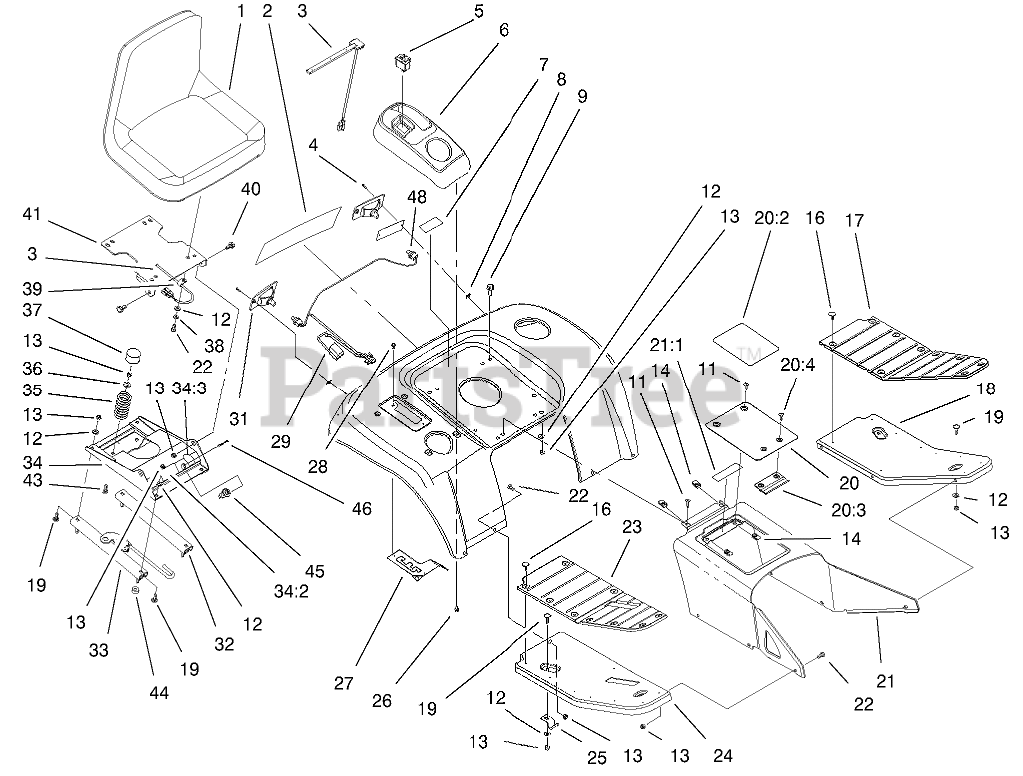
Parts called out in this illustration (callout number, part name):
1	SEAT
2	DECAL - FENDER
3	SWITCH-SEAT
4	SCREW-PPH
5	SWITCH-CRUISE
6	POD-CONTROL
7	DECAL - USA
8	NUT-SPEED
9	SCREW-HHF
11	SCREW-HH
12	WASHER-PLAIN
13	NUT-LOCK, NI
16	FASTENER-PANEL
17	PAD-FOOTREST, LH
18	FOOTREST-LH
19	SCREW-CARR
20	COVER / DECAL ASM
20:2	DECAL-DANGER
20:3	RETAINER-COVER
20:4	SCREW-PPH
21	TUNNEL ASM
21:1	DECAL-DANGER
22	SCREW-HH
23	PAD-FOOTREST, RH
24	FOOTREST-RH
25	BRACKET-FOOTREST
26	SCREW-HHFTF
27	GATE-HI / LO SHIFT
28	SCREW-HWH
29	HARNESS-REAR
31	LAMP-TAILLIGHT
32	SLIDE-SLAVE, SEAT
33	SLIDE-LATCH, SEAT
34	SEAT BASE ASM
34:2	DECAL-DANGER
34:3	DECAL
35	SPRING-COMPRESSION
36	BUSHING
37	CAP-SPRING, SEAT
38	WASHER-LOCK
39	CLAMP-R
40	BOLT-SHOULDER
41	Mount-Seat
43	SCREW-CARR
44	WASHER-FLAT
45	STARTER SWITCH ASM
46	KEY-IGNITION
48	LIGHT BULB
